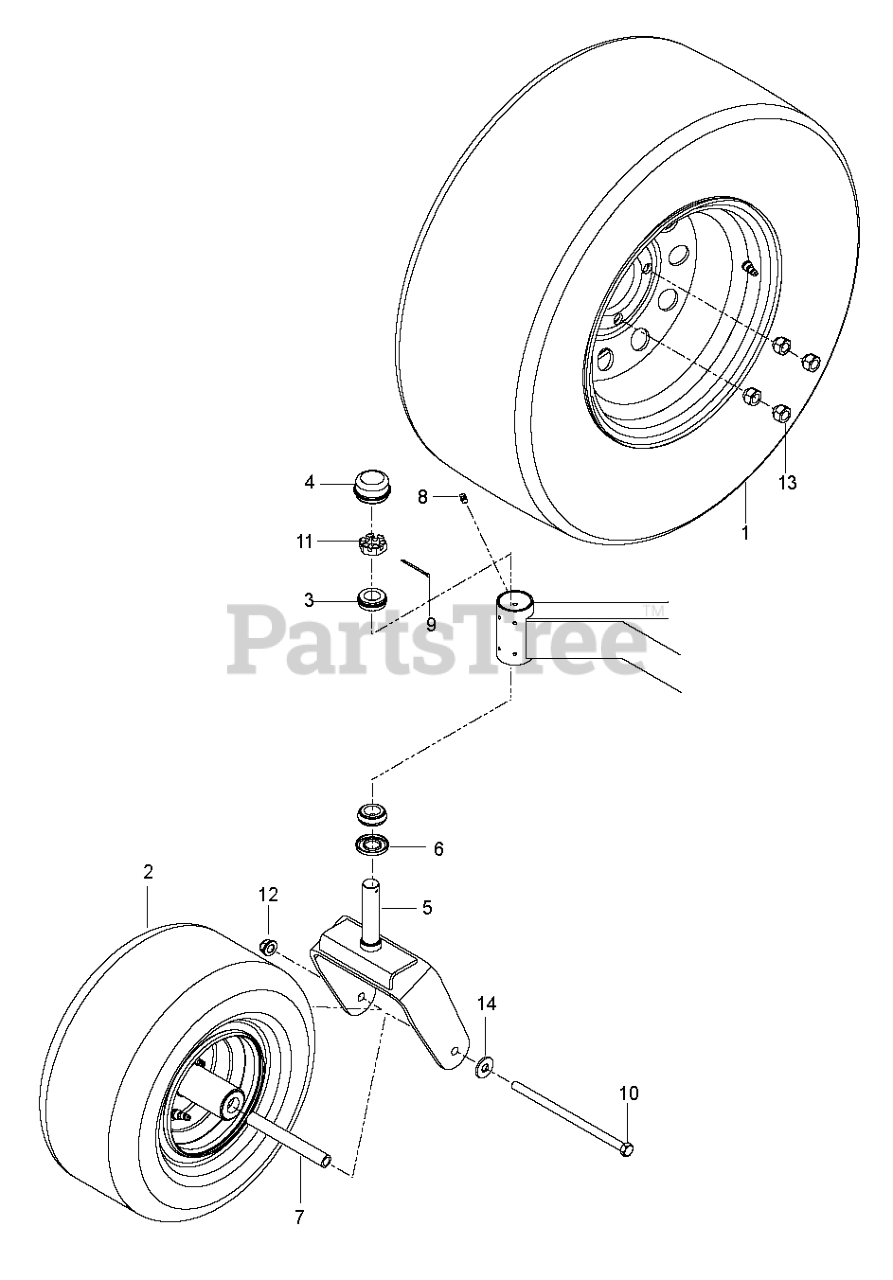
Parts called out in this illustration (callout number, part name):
1	TIRE TIRE & WHEEL ASSEMBLY BLA
2	WHEEL 13X5 ASSEMBLY GLOSS BLAC
3	TAPERED ROLLER BRG
4	GREASE CAP
5	FORK CASTER YOKE WELDMENT SNAP
7	SPACER, CASTER
9	COTTER PIN 1/8 X 2
10	HEX SCREW 1/2-13 X 9.5 GR5
11	NUT 1"C HEX SLOTTED
12	NUT, 1/2-13 HEX FLG NYLOC ZD
13	NUT.1/2-20.UNF-2B.GR.8.YL
14	WASHER.9/16 X 1 3/8 X 12 GA.
